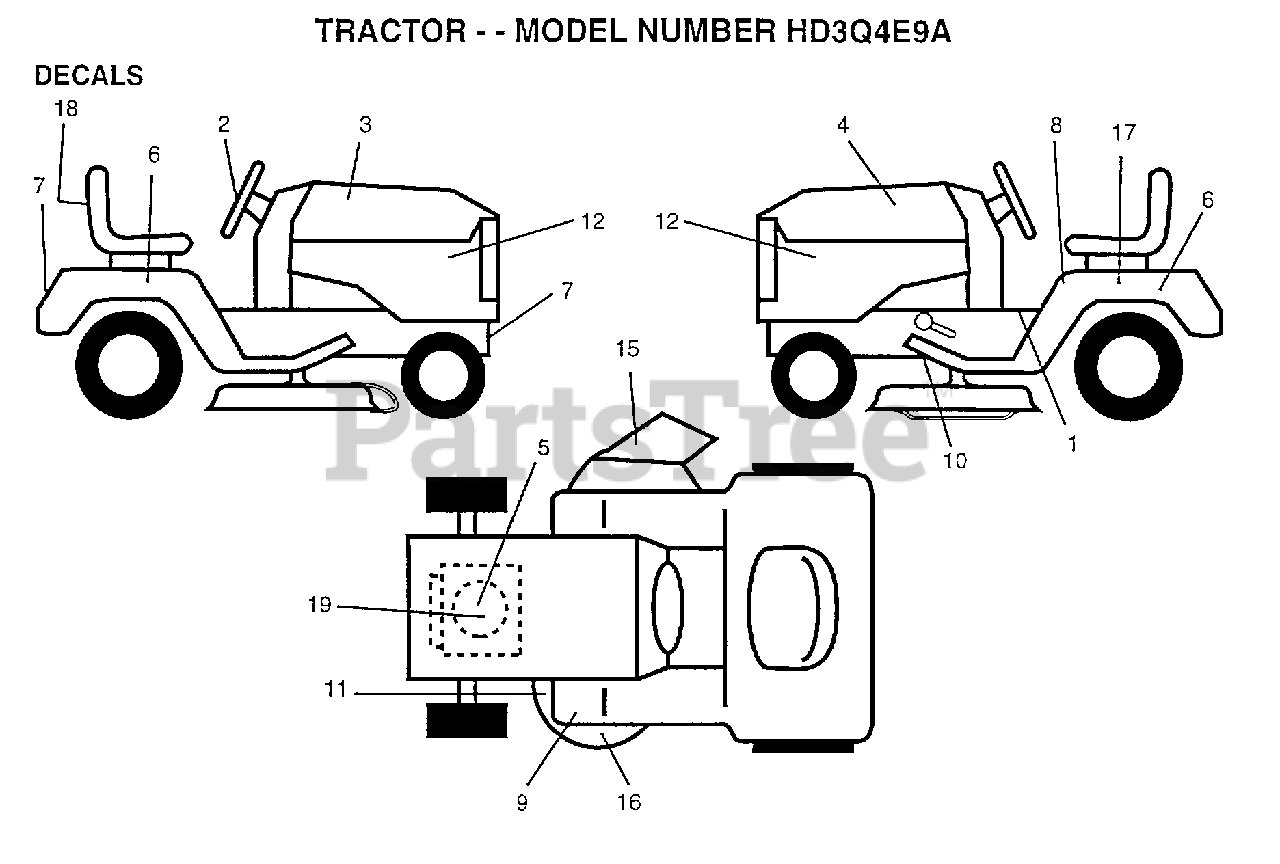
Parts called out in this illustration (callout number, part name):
1	DECAL.SADDLE.INST
2	DECAL.INST.WHL.ST
3	DECAL HOOD RH
4	DECAL HOOD LH
5	DECAL, HP, ENGINE
6	DECAL.FEND.QUICKS
7	DECAL.FENDER.HDEP
8	DECAL CAUT FEND
9	DECAL CLUT/BRAKE
12	DECAL.PNL.SD.HDPO
16	DECAL.DECK.MULCH.
17	DECAL.BTRY.DANGER
18	"DECAL, WARNING"
18	DECAL SEAT ACC
19	DECAL.PART.18.5HP
